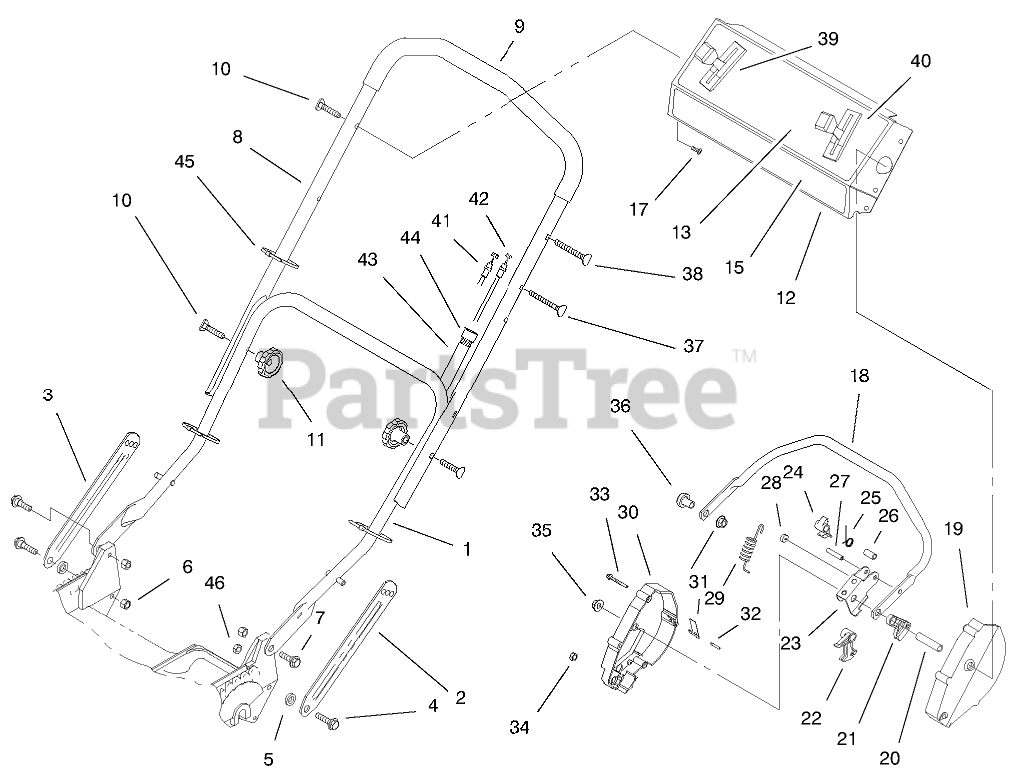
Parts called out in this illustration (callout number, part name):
1	ASM-Handle
2	Latch-Handle
3	Latch-Handle
4	SCREW-SHOULDER
5	SPACER
6	NUT-LOCK, NI
7	SCREW-SHOULDER
8	Handle-Upper
9	Grip-Foam
10	SCREW-HANDLE
12	Panel-Control(Incl. Ref. #13)
13	DECAL - INSRTUCTION
15	DECAL - CONSOLE
17	SCREW-TAP
18	Bar-Control
19	HOUSING-CONTROL, LH
20	TUBING-SPACER
21	LEVER-TRACTION
22	ROCKER
23	LEVER-CABLE
24	HOOK-CONTROL
25	SPRING-TORSION
26	SPACER
27	PIN-ROLL, SLOTTED
28	WASHER-NYLON
29	SPRING-DETENT
30	Housing-Control
31	SPRING-LEAF
32	PIN-INSERT
33	SCREW-HWHTF
34	NUT-LOCK NI
35	NUT-LOCK NI
36	SPACER-SUPPORT
37	SCREW-HANDLE
38	OBS MATERIAL EXCEPT FOR SERVICE
39	CONTROL-SPEED, GROUND
40	THROTTLE CONTROL
41	CLUTCH CABLE
42	TRACTION CABLE
43	CONTROL CABLE COVER
44	FITTING-RING
45	TIE-CABLE
46	NUT-LOCK, NI
